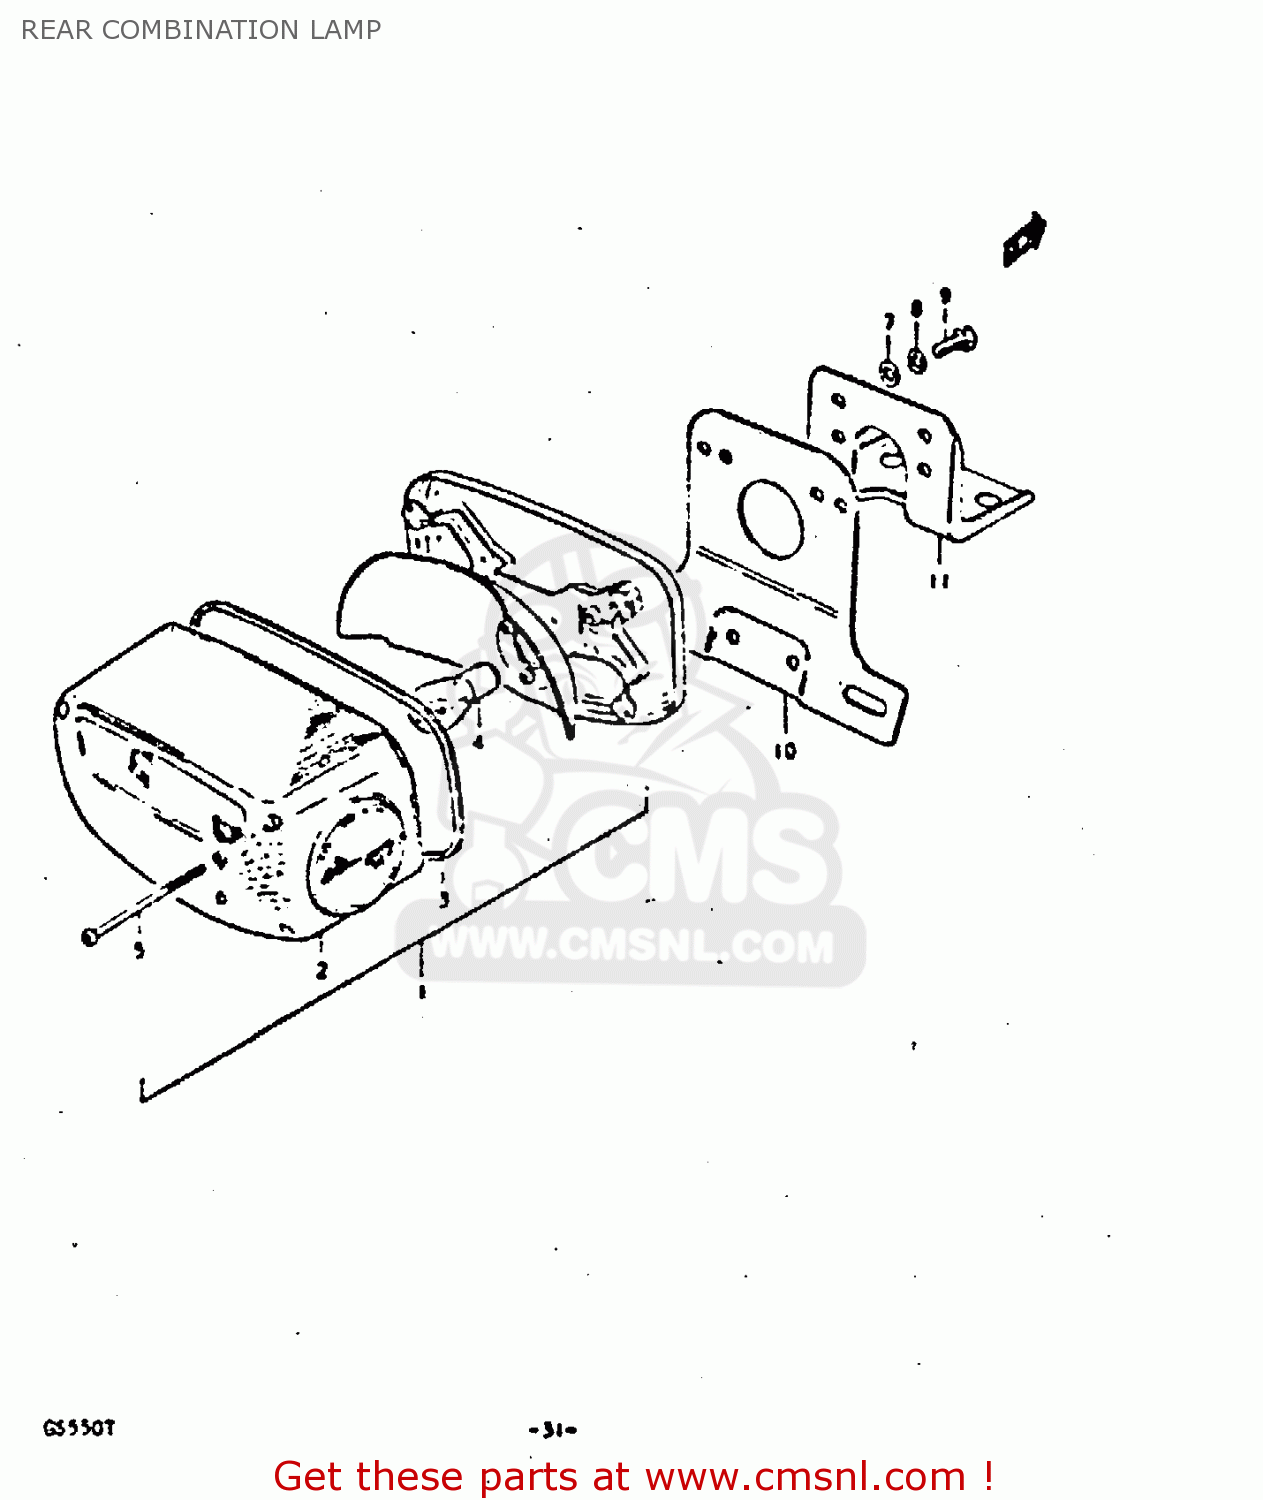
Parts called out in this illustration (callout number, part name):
1	LAMP ASSEMBLY,REAR COMBINATION
2	LENS,REAR COMBINATION LAMP
3	GASKET (NAS)
4	BULB (12V, 23/8W)
5	SCREW (4X55)
6	GASKET (NAS)
7	WASHER
8	LOCK WASHER
9	BOLT
10	BRACKET,LICENSE PLATE
11	BRACKET,LICENSE PLATE
